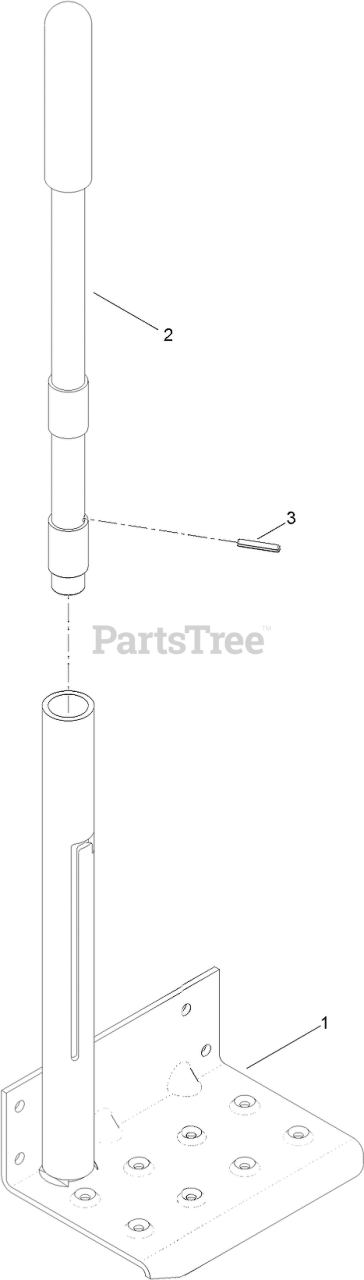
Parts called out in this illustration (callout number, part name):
1	HANDLE-LOWER
2	HANDLE ASM
3	PIN-SPRING
